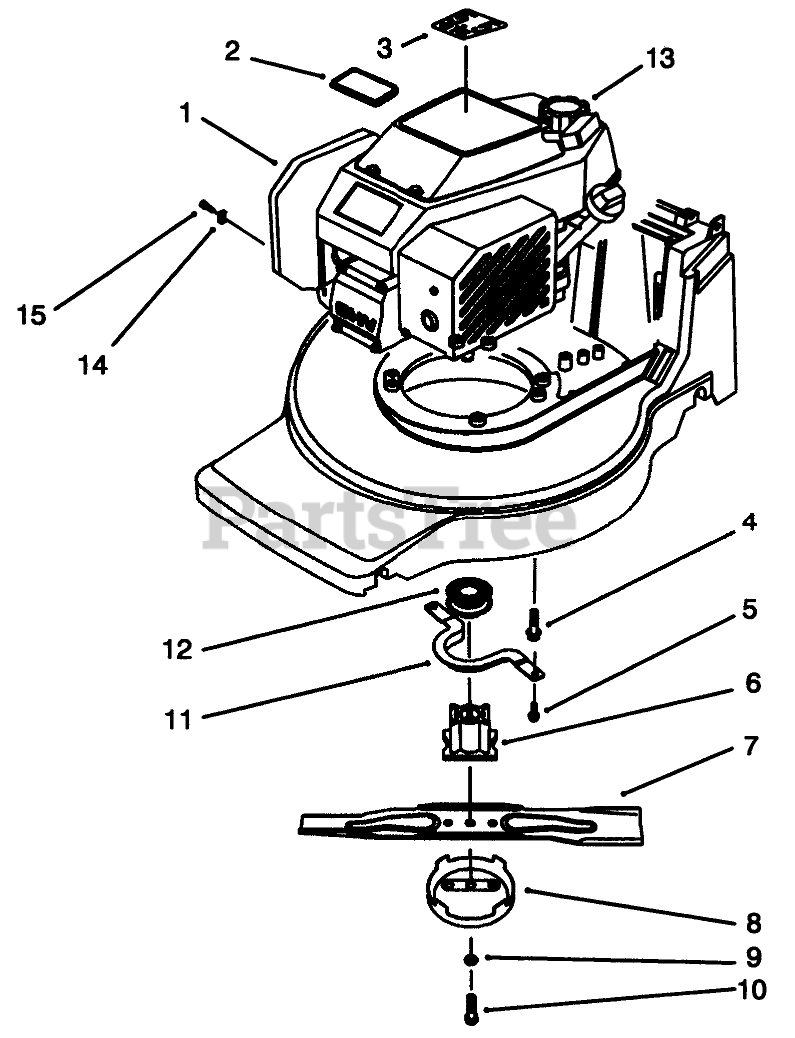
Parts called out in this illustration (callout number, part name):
1	ENG ASM-GTS150 KEY/NC
2	PLATE-LOGO
3	DECAL - ENGINE
4	SCREW-HWH
5	SCREW-HWH
6	BLADE RETAINER - 25 MM
7	Blade-48cm
8	CUP-SCALP, ANTI
9	WASHER-LOCK
10	BOLT-BLADE
11	Guide-Belt
12	PULLEY-DRIVE, ZONE START
13	GAS CAP ASM
14	CLAMP-CASING
15	CLAMP SCREW F/W ENGINE
